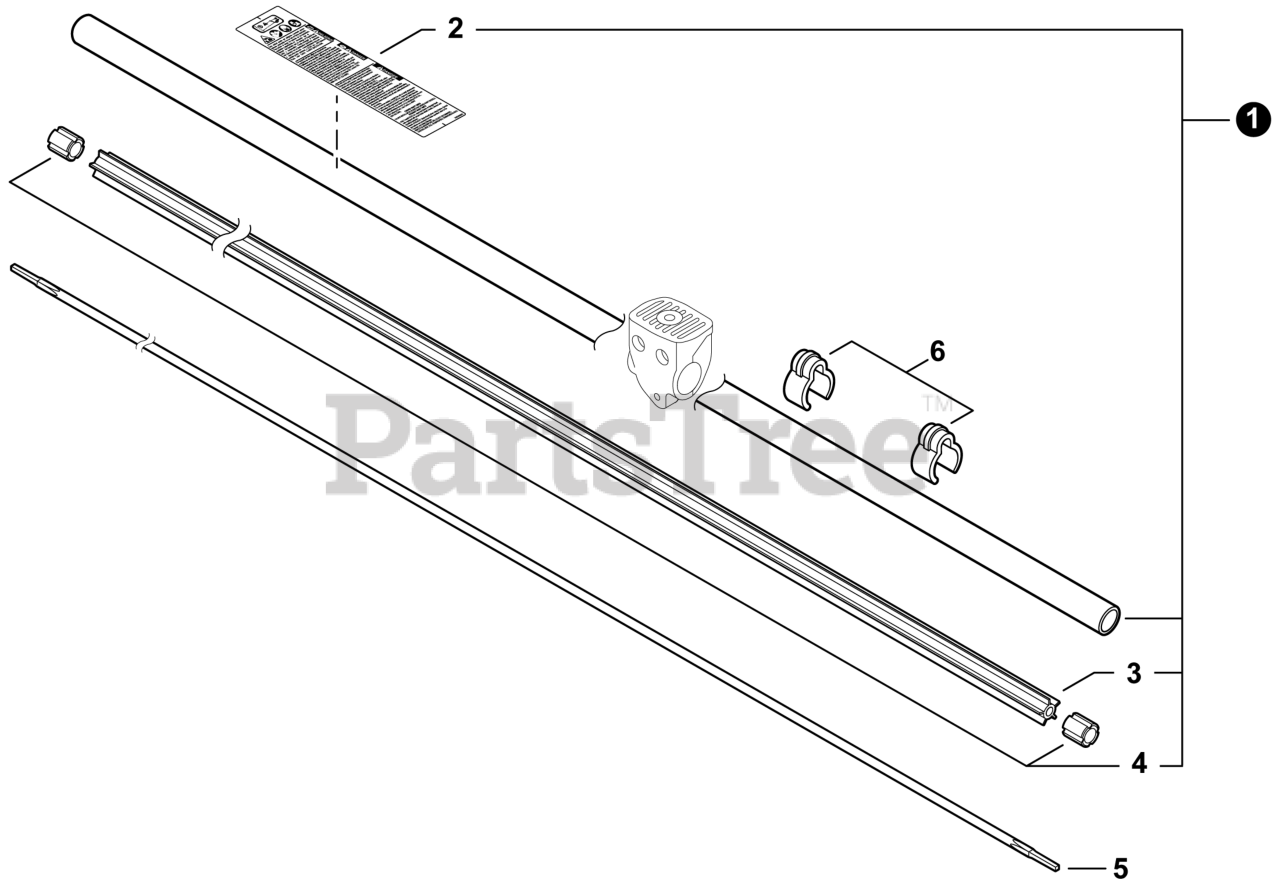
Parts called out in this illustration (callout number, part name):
1	MAIN PIPE ASSY
2	LABEL - CAUTION
3	LINER, FLEXIBLE 21.6×1420
5	DRIVESHAFT - FLEXIBLE
6	CLIP, CABLE 25 MM
